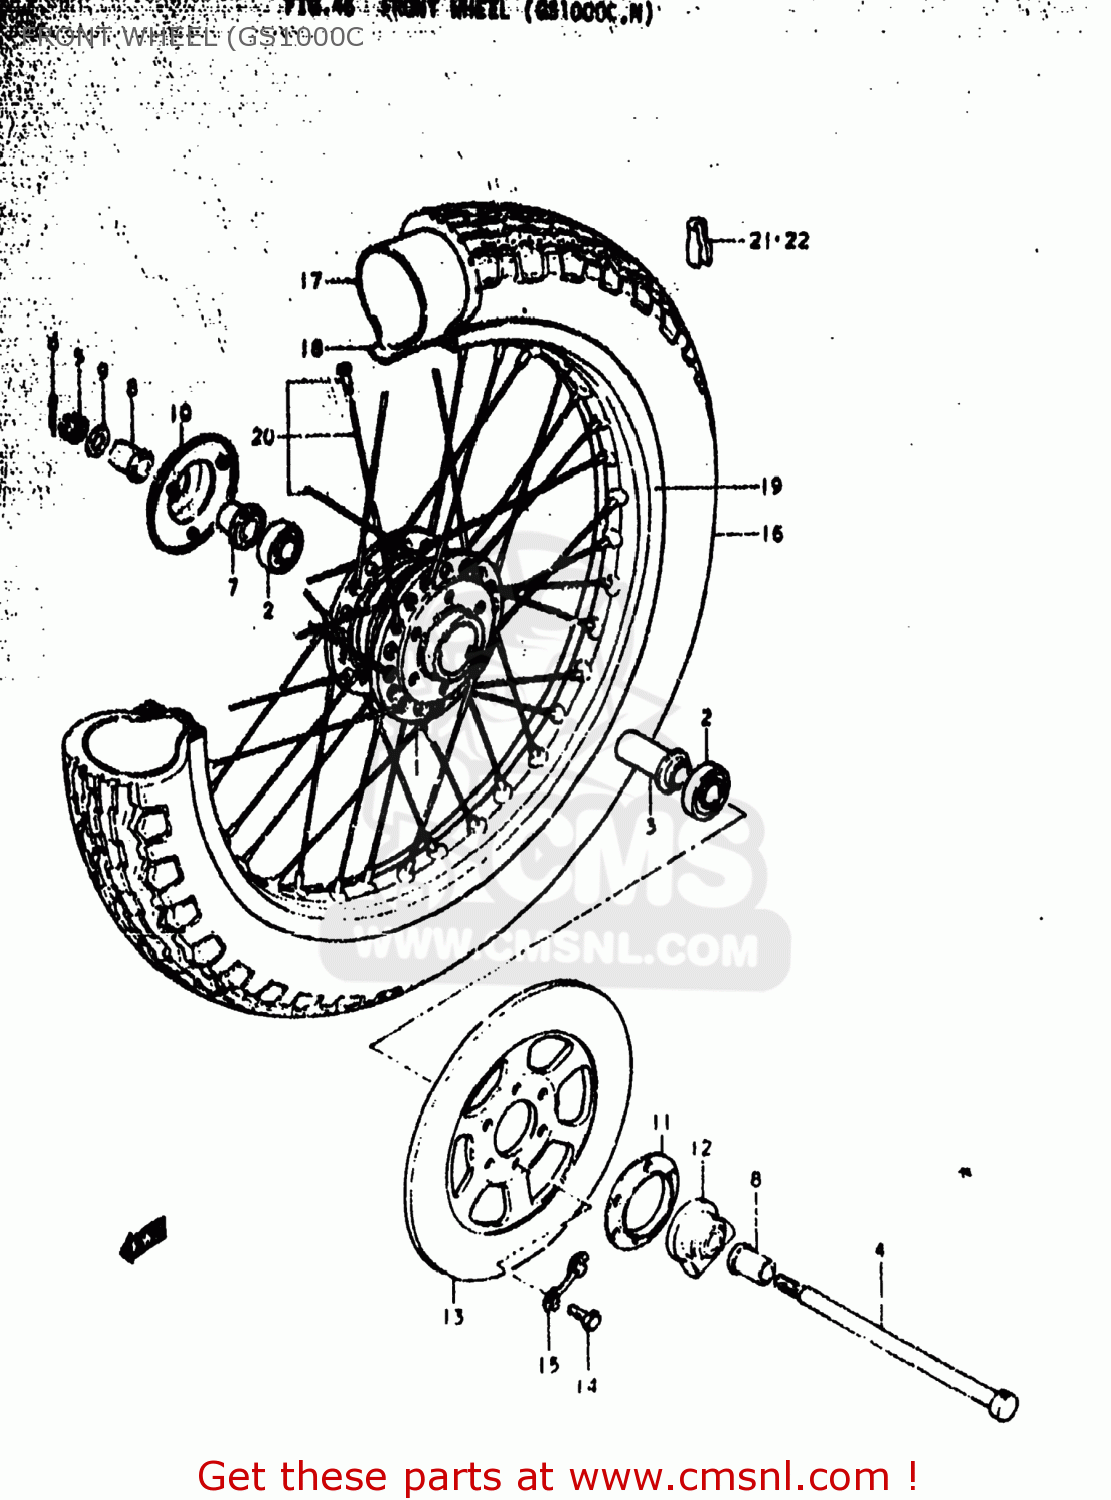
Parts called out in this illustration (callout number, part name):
1	DRUM,FRONT HUB
2	BEARING
3	SPACER,FR HUB BEARING
4	AXLE,FR
5	NUT 12MM
6	COTTER PIN
7	SPACER,FR AXLE,R
8	SPACER,FR AXLE,L
9	WASHER
10	COVER,FR HUB,R
11	DUST SEAL,SPEEDOMETER GEAR BOX
12	BOX ASSEMBLY,SPEEDOMETER GEAR
13	DISC,BRAKE
14	BOLT(8X25)
15	WASHER
16	TIRE,FRONT
17	TUBE,INNER
18	PROTECTOR,WHL INR TUBE
19	RIM,FRONT WHEEL
20	SPOKE SET,FRONT
21	BALANCER,WHEEL (B)
22	BALANCER,WHEEL (30G)
